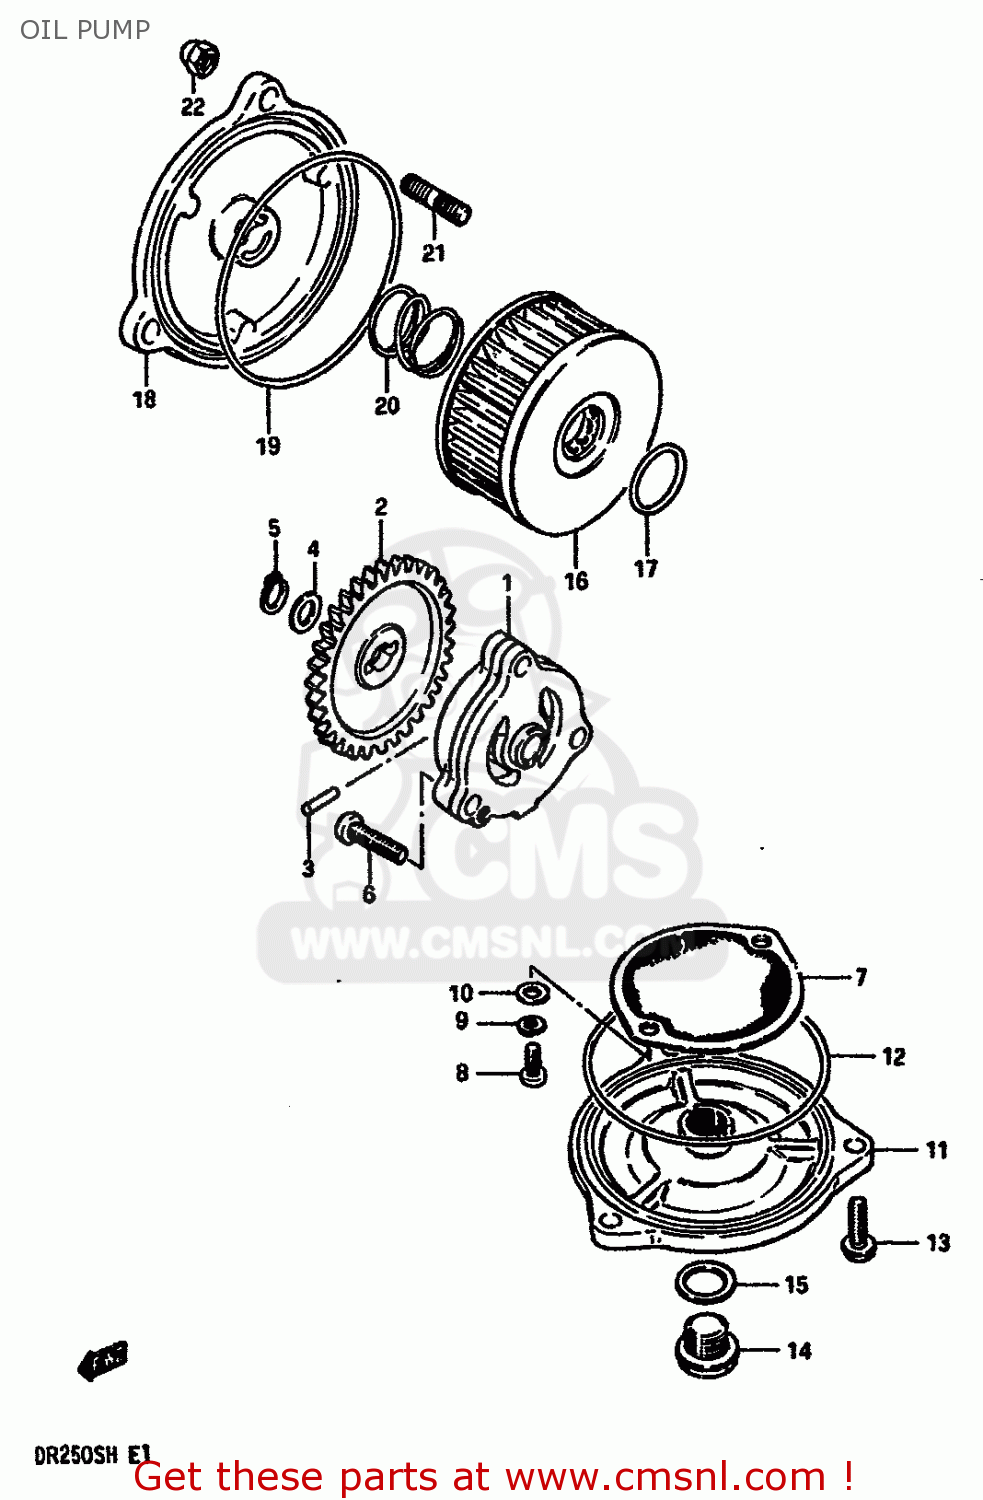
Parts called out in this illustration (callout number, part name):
1	PUMP ASSY,ENGINE OIL
2	GEAR,OIL PUMP DRIVEN(NT:33)
3	PIN(4X15.8)
4	SHIM
5	CIRCLIP
6	SCREW
7	STRAINER,ENGINE OIL
8	SCREW 5X12
9	LOCK WASHER
10	WASHER
11	CAP,OIL STRAINER
12	O RING(D:2.4,ID:85)
13	BOLT (6X20)
14	PLUG
15	GASKET(14X19.2X2) (NAS)
16	FILTER ASSY,ENGINE OIL
17	O RING(D:2.4,ID:15.8)
18	CAP,OIL FILTER
19	O RING(D:2.4,ID:73)
20	SPRING
21	STUD 6X12
22	NUT 6MM
